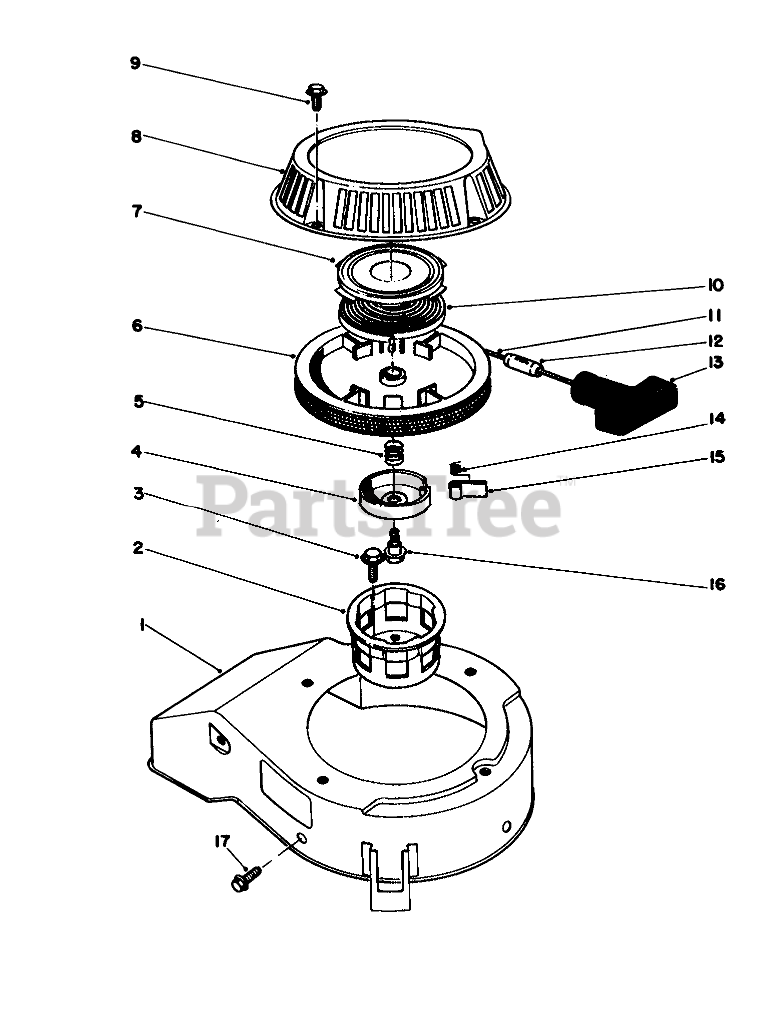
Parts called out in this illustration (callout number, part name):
1	COVER
2	CUP - STARTER
4	RETAINER
5	SPRING
7	Retainer-Recoil Spring
9	SCREW-HHF
10	Spring-Recoil
11	ROPE-STARTER
13	HANDLE-RECOIL
14	SPRING
